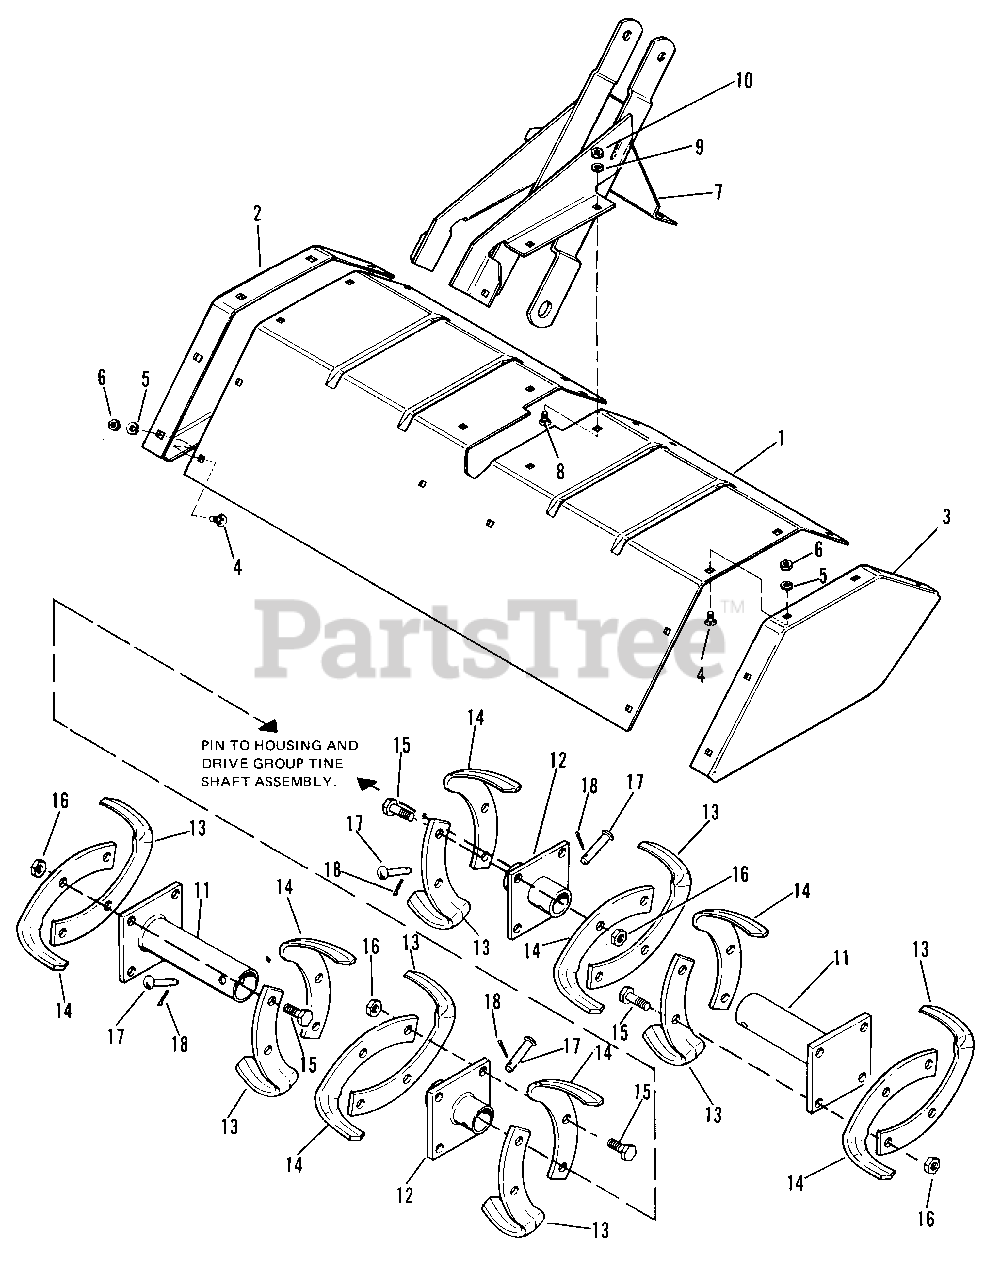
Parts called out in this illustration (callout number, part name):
1	DEFLECTOR
2	DEFLECTOR, End plate, L.H.
3	DEFLECTOR, End plate, R.H.
4	BOLT, Carriage, 5/16-18 x 1/2
5	LOCKWASHER, 5/16
6	NUT, hex, 5/16-18
7	SUPPORT ASSEMBLY
8	BOLT, Carriage, 5/16-18 x 3/4
9	LOCKWASHER, 5/16
10	NUT, hex, 5/16-18
11	TINE HUB ASSEMBLY
12	INNER TINE PLATE ASSY.
13	TINE BLADE L.H.
14	TINE BLADE R.H.
15	CAPSCREW, Hex, 7/16-20 x 1-1/4
16	LOCKNUT, hex, 7/16-20
17	PIN
18	PlN, Cotter, 1/8 x 3/4
